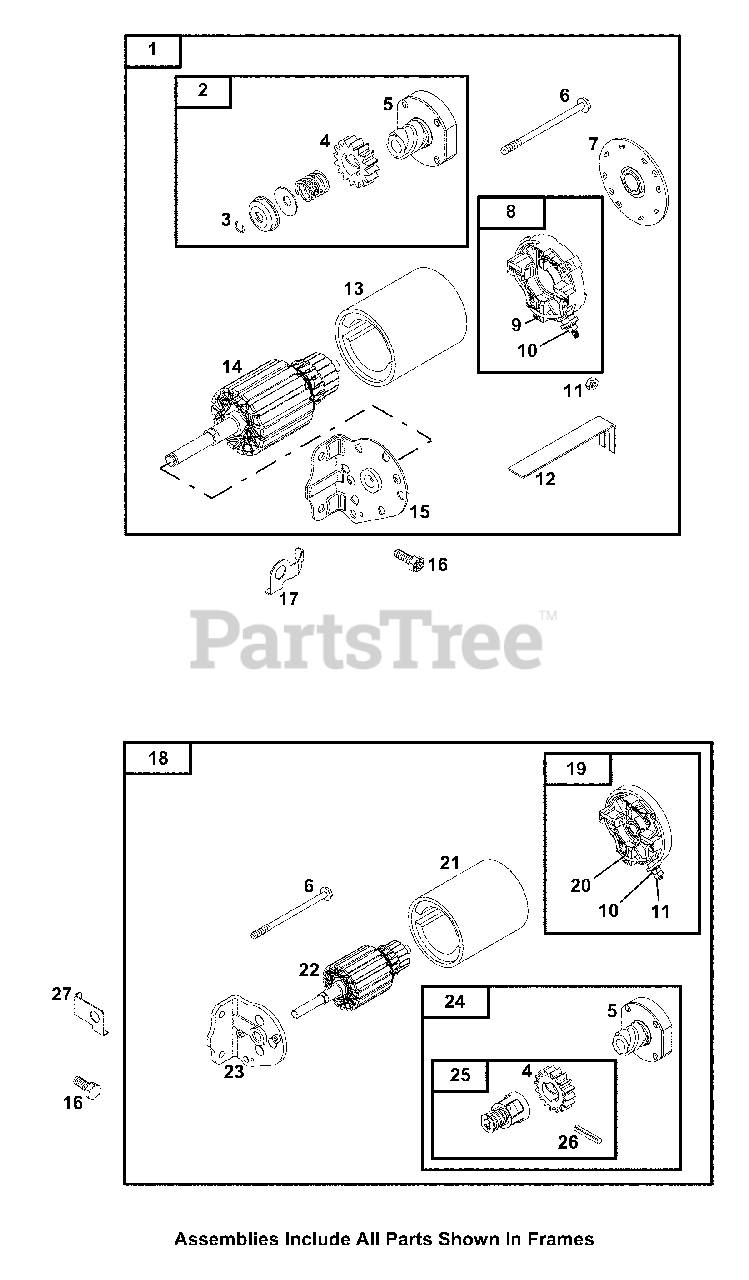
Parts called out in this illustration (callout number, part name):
1	Motor-Starter
2	Drive-Starter
3	Ring-Retaining
4	Gear-Pinion
5	Clutch-Drive
6	Bolt (Starter Motor)
8	Retainer-Brush
10	Nut (Brush Retainer)
11	Nut (Brush Retainer)
12	Starter Strap
13	Housing-Starter
14	Armature-Starter
15	Cap-Drive
16	Screw (Drive Cap)
21	Housing-Starter
22	Armature-Starter
24	Drive-Starter
25	Kit-Gear
26	Pin-Roll
